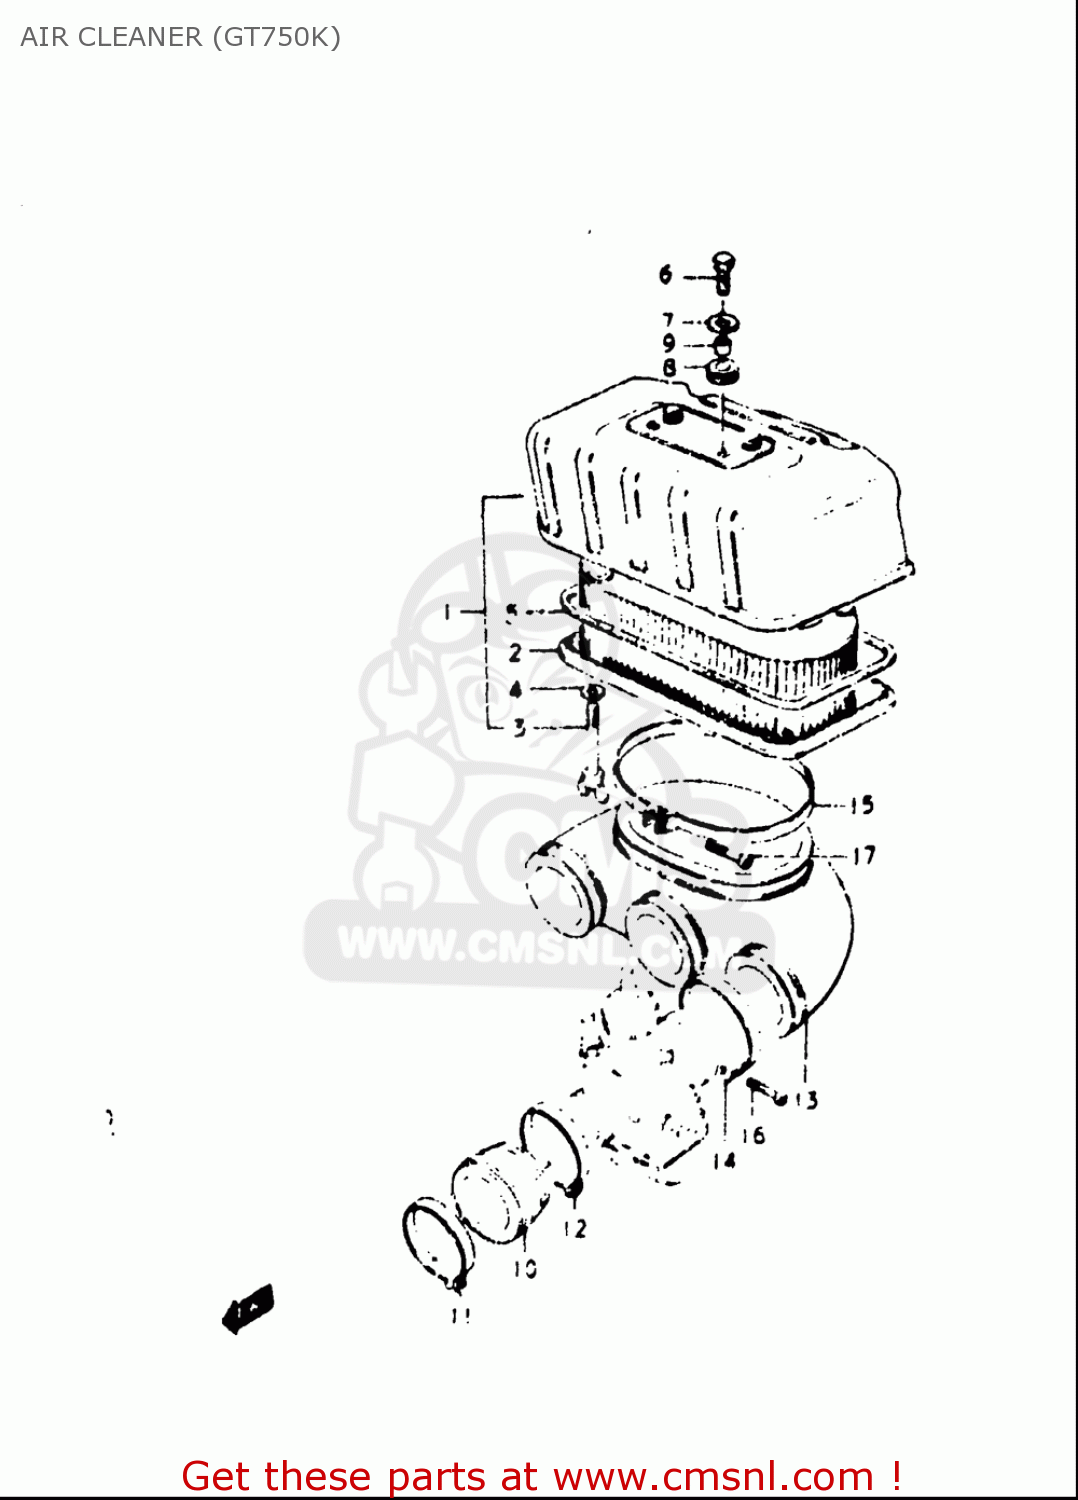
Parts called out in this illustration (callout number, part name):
2	FILTER ASSY
4	WASHER
6	BOLT
7	WASHER(6.5X20X1.2)
8	CUSHION
10	PIPE,INTAKE
11	CLAMP
12	CLAMP
14	CLAMP
16	SCREW
